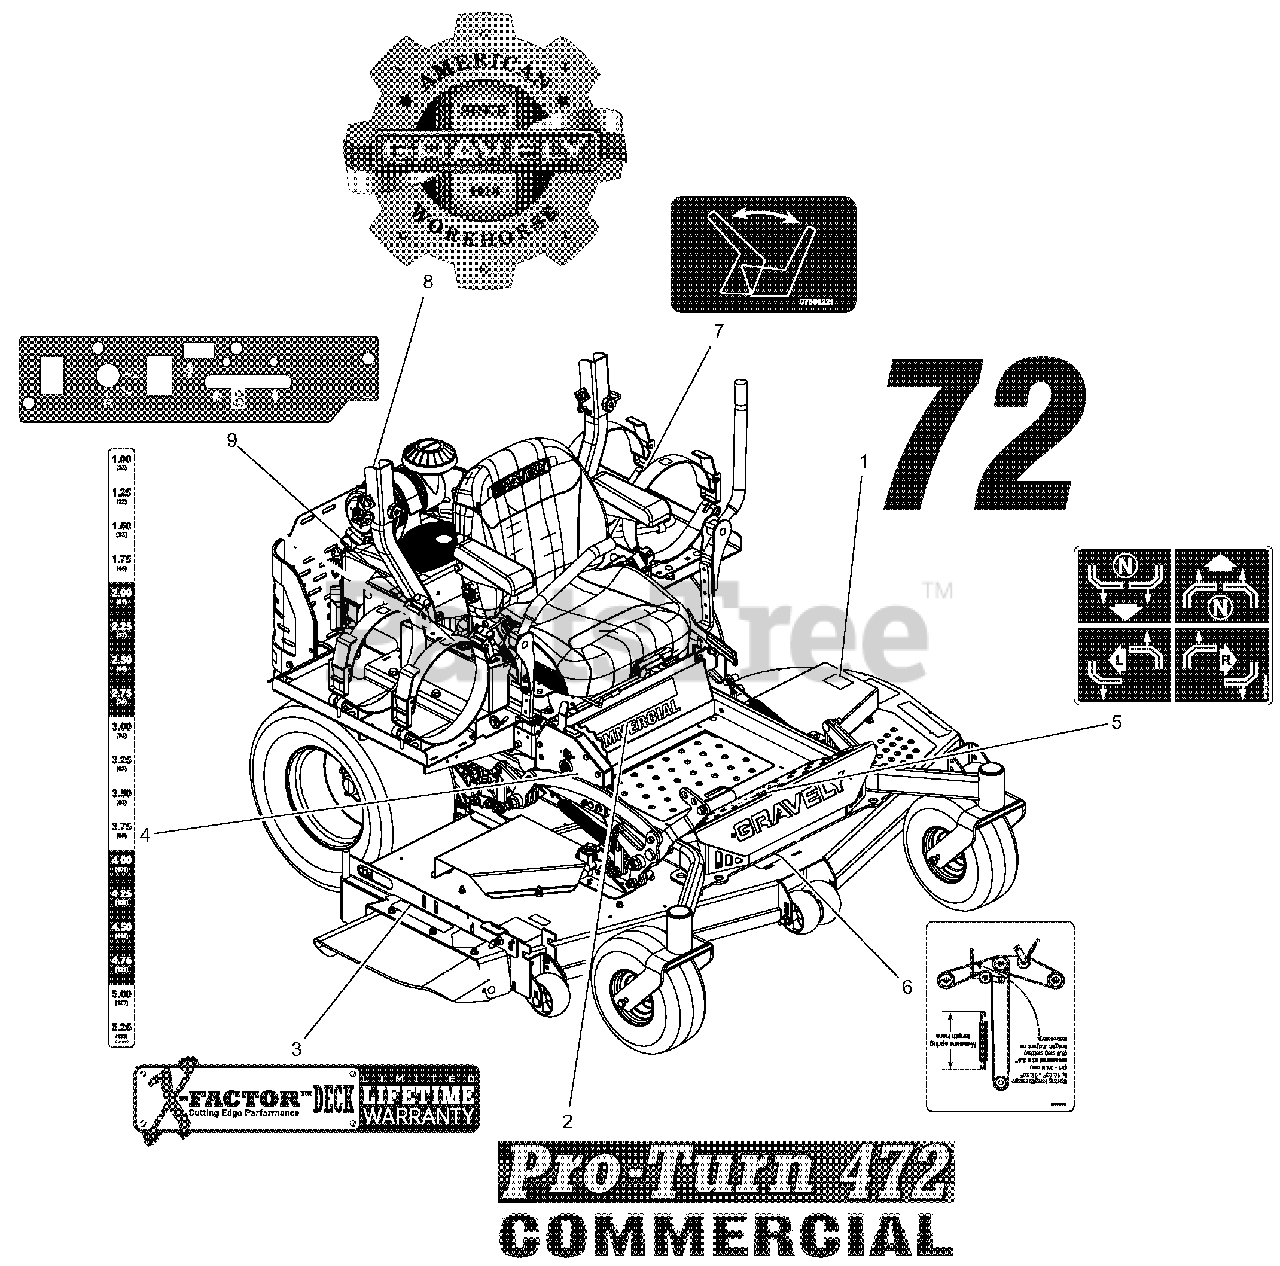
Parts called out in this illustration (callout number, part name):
1	DECAL, 72"
2	DECAL, PRO-TURN 272
3	DECAL, X-FACTOR DECK
4	DECAL, PT400 HEIGHT OF CUT
5	DECAL, INSTRUCTIONAL - STEERING
6	DECAL, BELT DIAGRAM 60"
7	DECAL, SEAT RELEASE
8	DECAL, GRAVELY HERITAGE-LARGE
9	DECAL, CONTROL PT40P0 - L
